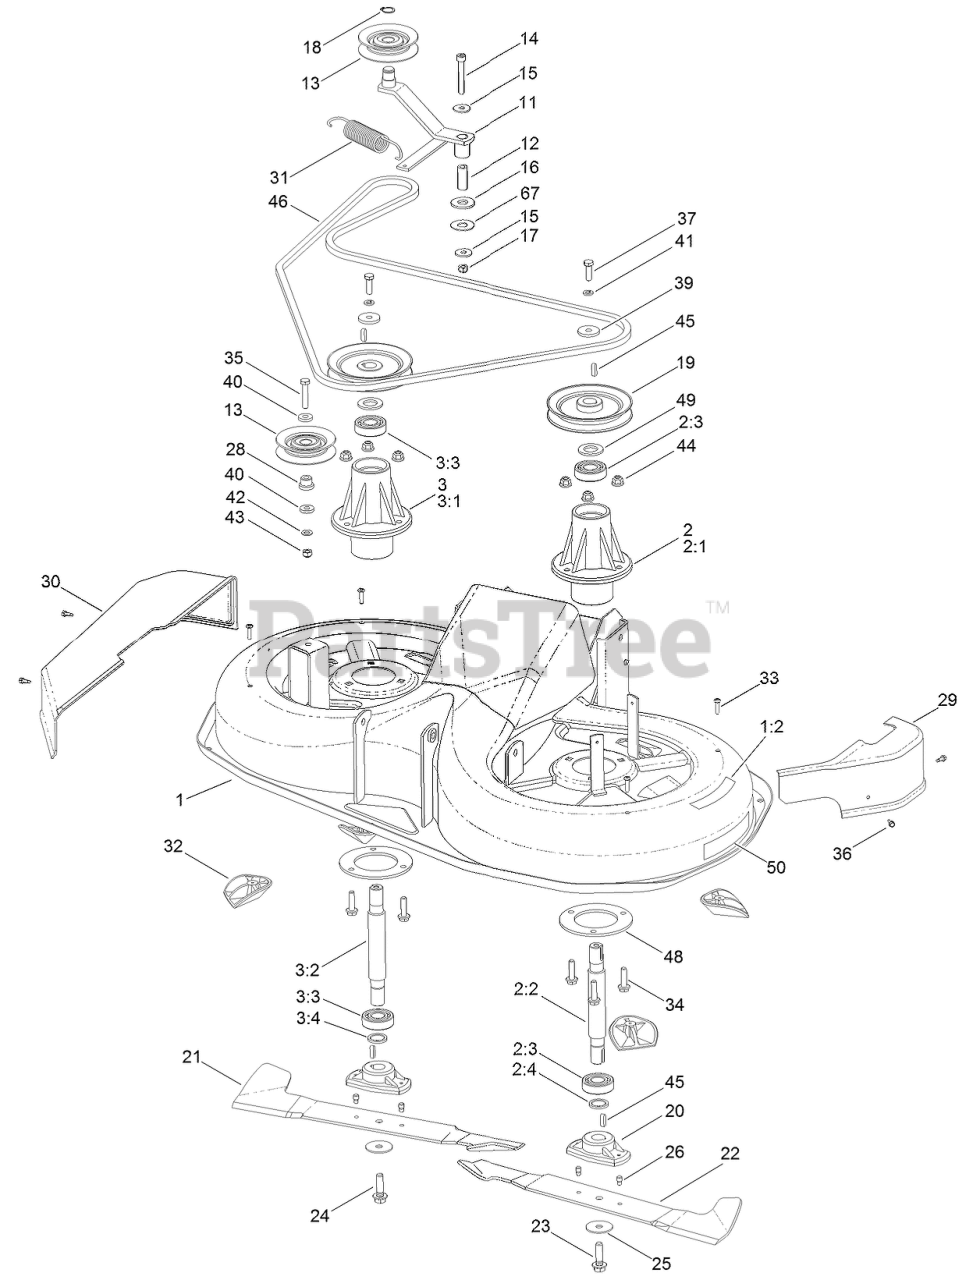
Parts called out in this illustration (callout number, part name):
1	DECK ASM
1:2	DECAL-DANGER
2	LEFT SPINDLE ASM
2:1	HOUSING-SPINDLE
2:2	SHAFT-BLADE, LEFT
2:3	BEARING
2:4	RING-LOCK
3	RIGHT SPINDLE ASM
3:1	HOUSING-SPINDLE
3:2	SHAFT-BLADE, RIGHT
3:3	BEARING
3:4	RING-LOCK
11	ARM-IDLER
12	SPACER
13	PULLEY-IDLER
14	BOLT-HH
15	WASHER-PLAIN
16	WASHER-PLAIN
17	NUT-LOCK, NI
18	RING-LOCK
19	PULLEY-MOWING BELT, 4.5IN
20	ADAPTER-MOUNT, BLADE
21	BLADE-RH
22	BLADE-LH
23	SCREW-HEX
24	SCREW-HH, LEFT
25	WASHER-BELLEVILLE
26	PIN-SHEAR, GROOVED
28	BUSHING
29	GUARD-BELT, LEFT
30	GUARD-BELT, RIGHT
31	SPRING
32	KICKER
34	SCREW-HHF
35	SCREW-HH
37	SCREW-HH
39	WASHER
40	Washer-Flat
41	WASHER-SPRING
42	WASHER-PLAIN
43	NUT-LOCK, NI
44	NUT-LOCK, HHF
46	BELT-WEDGE, DOUBLE
48	SUPPORT-RING
49	WASHER-PLAIN
50	DECAL-RECYCLER
67	WASHER
